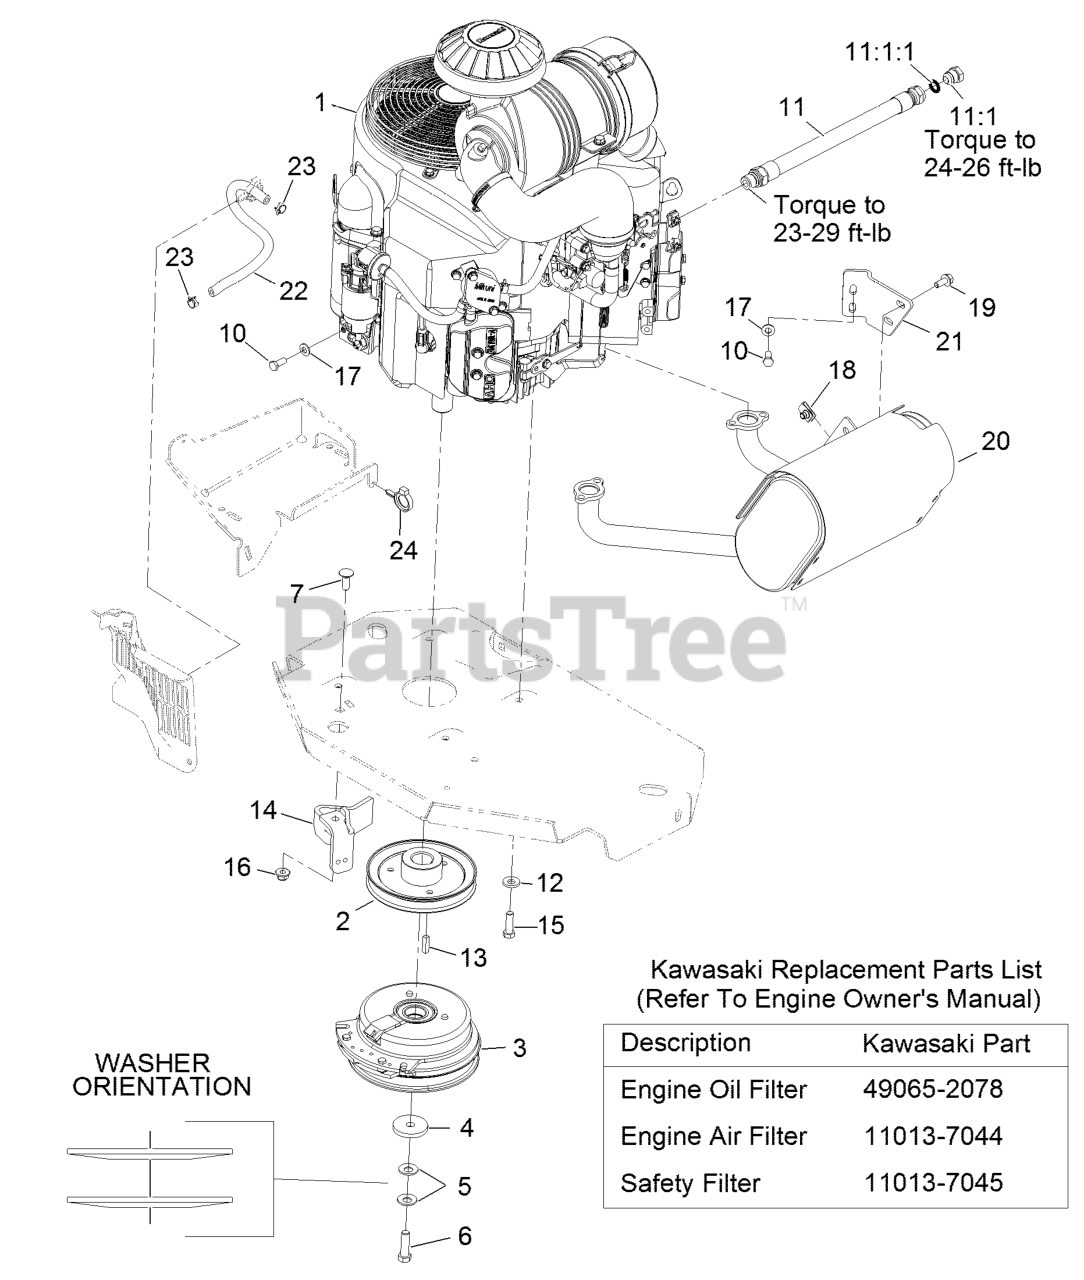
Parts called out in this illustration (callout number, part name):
2	SHEAVE
3	CLUTCH KIT
4	WASHER-CLUTCH
5	WASHER-SPRING
6	SCREW-HH 7/16-20 X 1 1/2 W/LOCTITE
7	SCREW-CARR
10	SCREW-HH
11	ENGINE OIL DRAIN HOSE ASM
11:1	PLUG-HH
11:1:1	O-RING
12	WASHER-BELLEVILLE
14	CLUTCH-ANCHOR
15	SCREW-HH
16	NUT-HF, NI
17	WASHER-SPRING
19	SCREW-HHF
20	MUFFLER
21	BRACKET-MUFFLER
22	HOSE-FUEL
23	CLAMP-HOSE
24	CLAMP-HOSE
